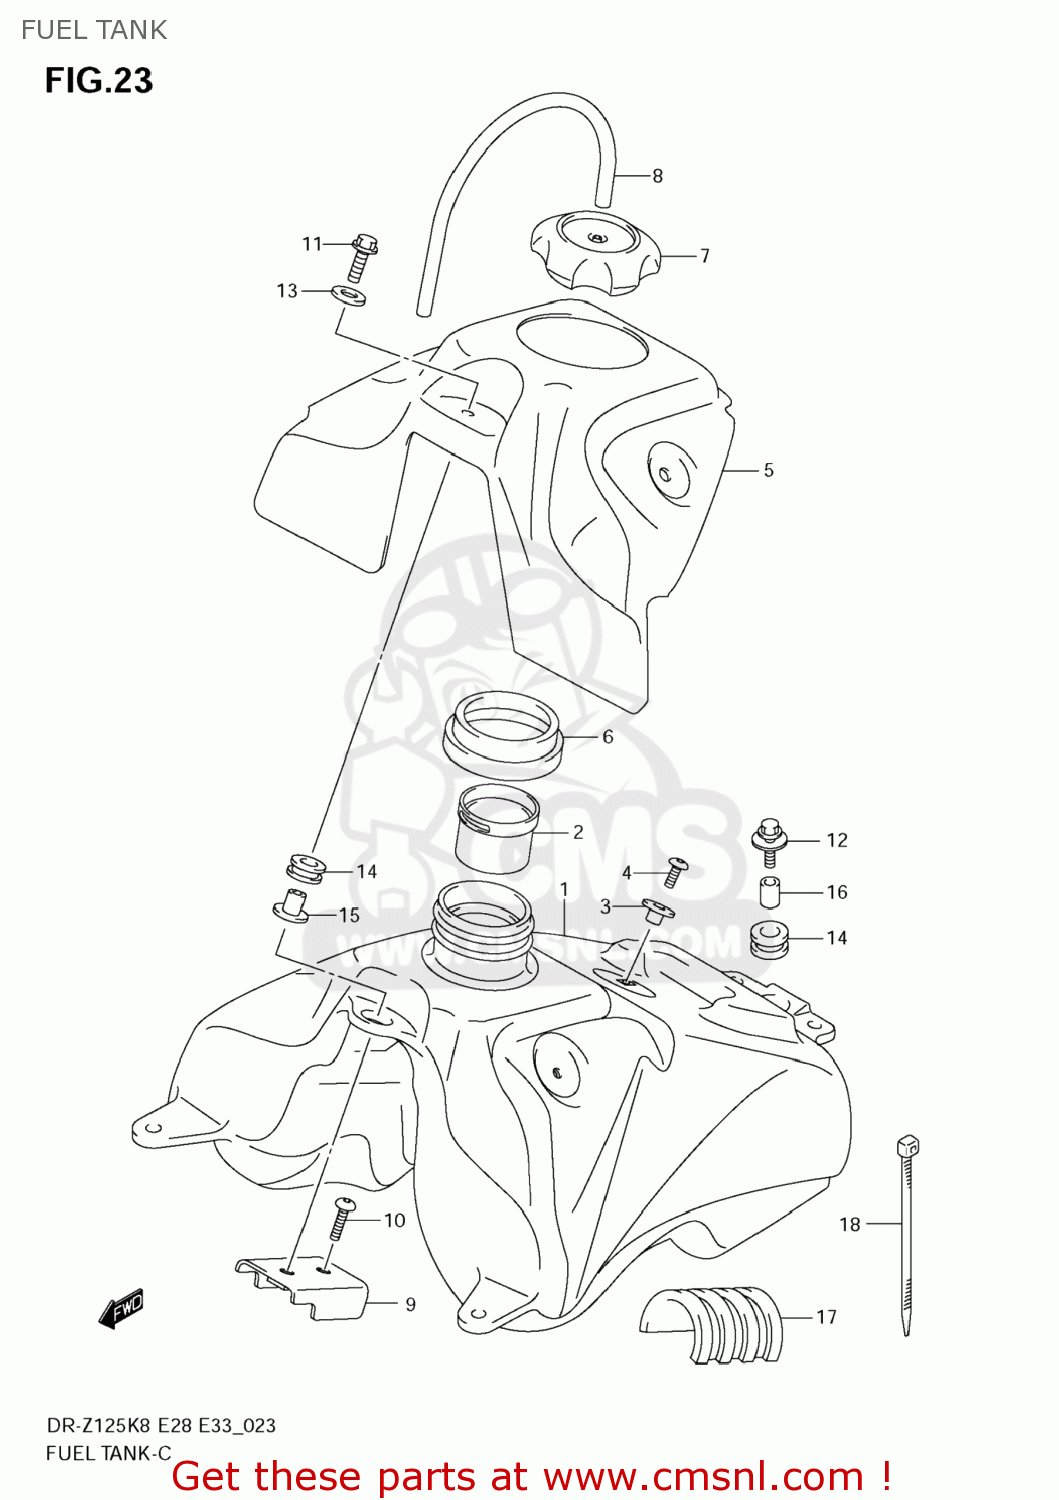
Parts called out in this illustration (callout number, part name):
1	TANK,FUEL
2	TUBE,FILLER INLET
3	HOOK,SEAT FR
4	BOLT(6X20)
5	COVER,FUEL TANK UPR
6	RUBBER,FUEL TANK INLET
7	CAP ASSY,FUEL TANK FILLER
8	HOSE(5X8.2X600)
9	BRACKET,FUEL TANK UPR
10	SCREW(6X10)
11	BOLT
12	BOLT(6X25)
13	WASHER(6.5X24X1.6)
14	CUSHION,FUEL TANK
15	WASHER,FUEL TANK FR
16	SPACER(6.5X10X14)
17	CUSHION,FUEL TANK
18	CLAMP(L:300)
